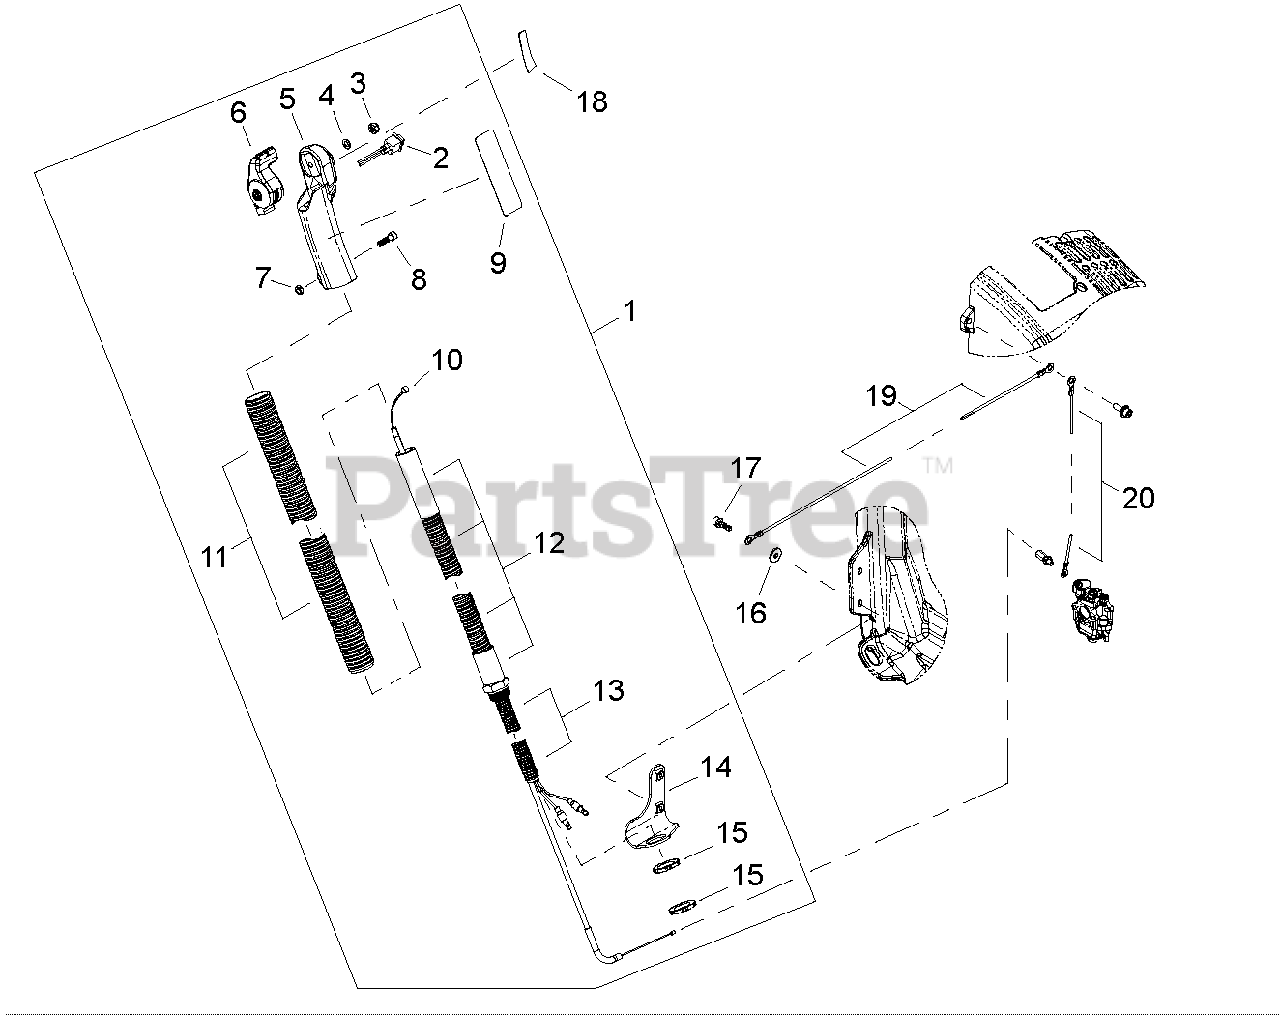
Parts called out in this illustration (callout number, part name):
1	THROTTLE CONTROL ASSY
2	SWITCH, ON-OFF
3	U-NUT M5
4	WASHER 5 MM
5	GRIP
6	CONTROL, THROTTLE
7	NUT M5
8	BOLT M5×16
9	PLATE, GROUND
10	CABLE, THROTTLE
11	TUBE, OUTER FLEX
12	ARM, FLEX
13	TUBE, FLEXIBLE
14	BRACKET, MOUNTING
15	NUT
16	WASHER Ø15ר5.2×1.6
17	BOLT, ADHESIVE M5×18
18	LABEL, THROTTLE
19	LEAD 0.75 MM2 L= 590
20	WIRE, STATIC DISCHARGE 110 MM
